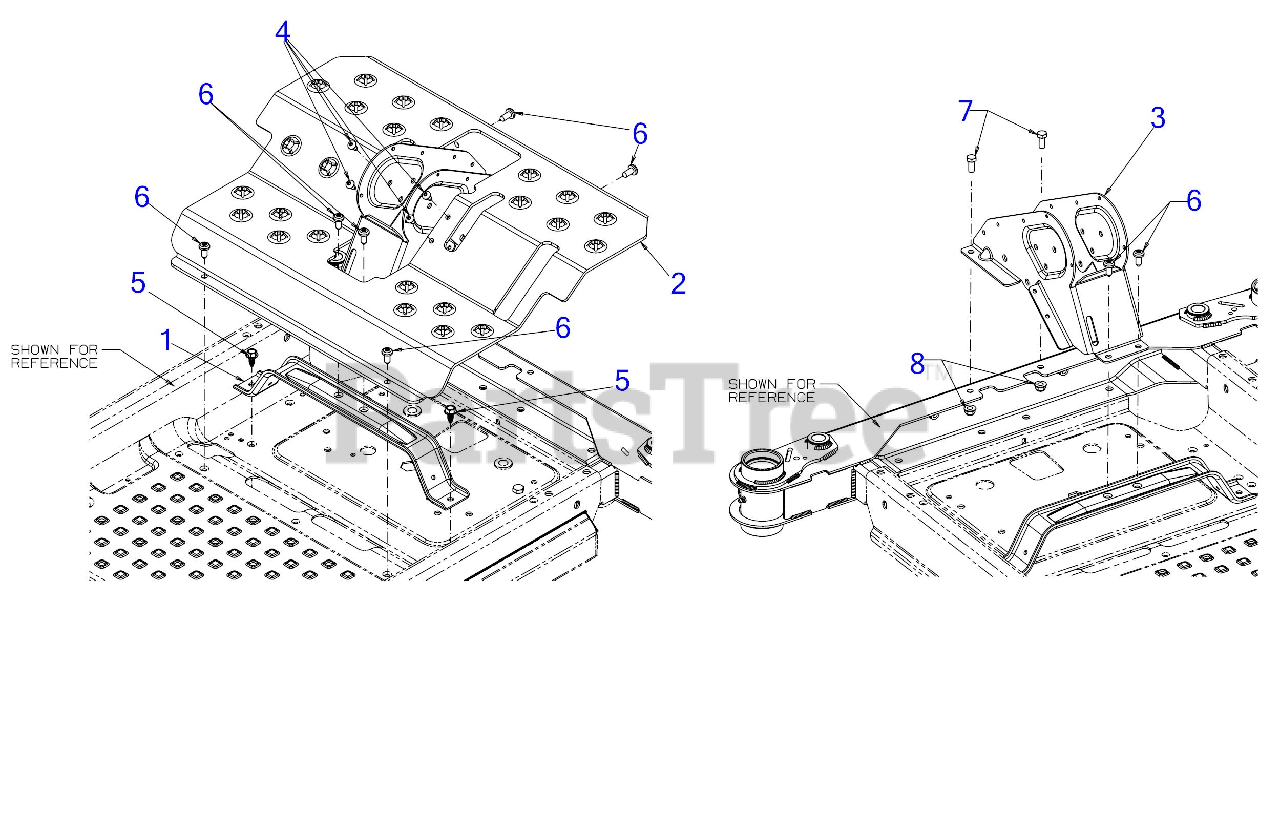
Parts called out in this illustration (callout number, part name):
4	SCREW 1/4-20 x .500
5	SCREW 5/16-18 x .750
6	SCREW 5/16-18 x .750
7	SCREW 5/16-18 x .75 GR5
8	FLANGE LOCK NUT 5/16-18
